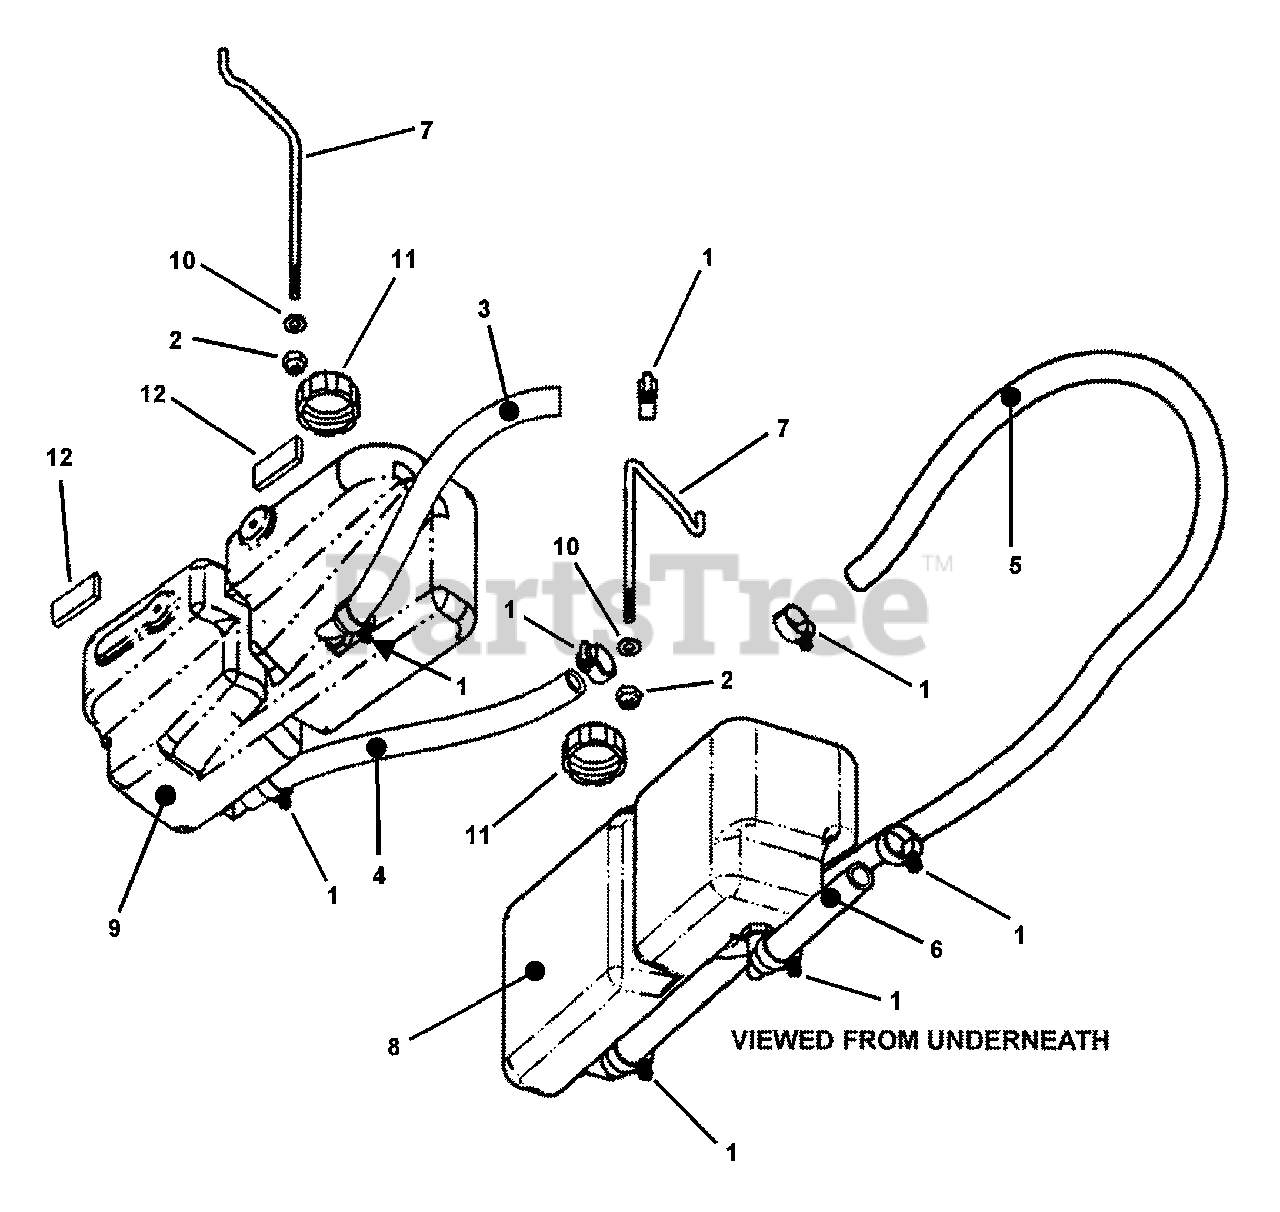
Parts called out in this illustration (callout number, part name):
1	CLAMP, Hose 13/16"
2	NUT, 5/16-18 HEX NYLON LOCK
3	HOSE, Rubber R.H. Front (5/8" I.D. x 13-1/2")
4	HOSE, Rubber R.H. Back (5/8" I.D. x 16")
5	HOSE, Rubber L.H. Front (5/8" I.D. x 34")
6	HOSE, Rubber L.H. Back (5/8" I.D. x 6")
7	BRACKET, Reservoir
8	RESERVOIR, L.H. Hydro
9	RESERVOIR, R.H. Hydro
10	WASHER, 11/32" I.D. x 11/16" O.D.
11	CAP, Reservoir
12	PAD, Tank
